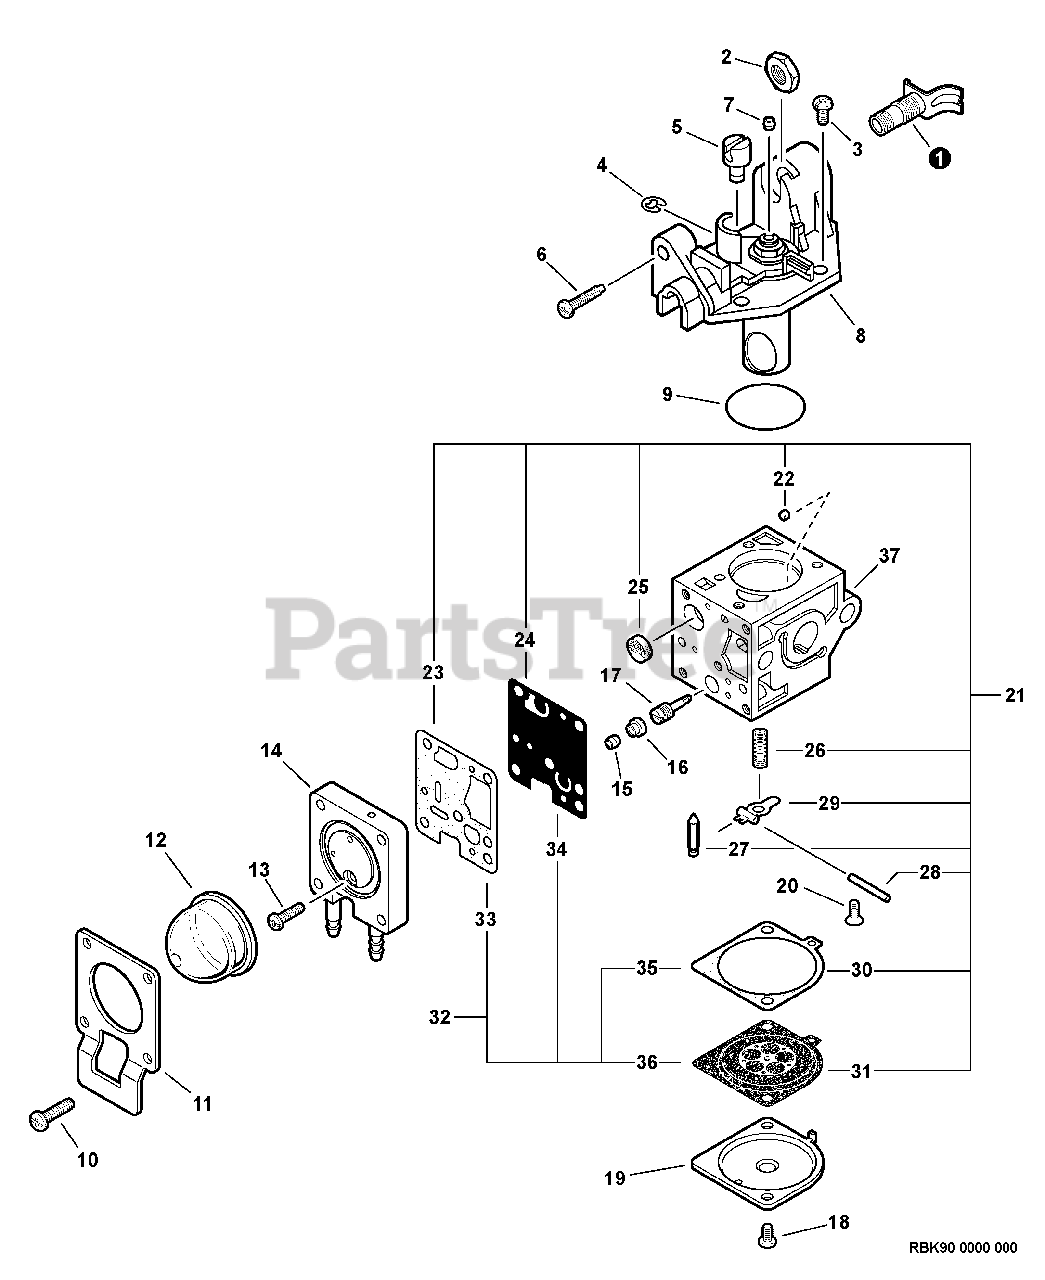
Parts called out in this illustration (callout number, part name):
1	GUIDE, CABLE
4	RING, RETAINING
6	SCREW, IDLE ADJUST
8	ROTOR COVER ASSY
10	SCREW, RETAINER
11	RETAINER, PURGE BULB
12	BULB, PURGE
13	SCREW, PURGE BASE
14	BASE, PURGE
16	CAP, LIMITER
17	NEEDLE - HIGH SPEED
19	COVER, METERING
20	SCREW, METERING LEVER PIN
21	REPAIR KIT
22	GUIDE, ROLLER
23	GASKET, PUMP
24	DIAPHRAGM, PUMP
25	STRAINER
26	SPRING, METERING LEVER
27	VALVE, INLET NEEDLE
28	PIN, METERING LEVER
29	LEVER, METERING
30	GASKET, METERING
31	DIAPHRAGM, METERING
32	DIAPHRAGM/GASKET KIT
33	GASKET, PUMP
34	DIAPHRAGM, PUMP
35	GASKET, METERING
36	BODY, CARBURETOR
37	DIAPHRAGM, METERING
